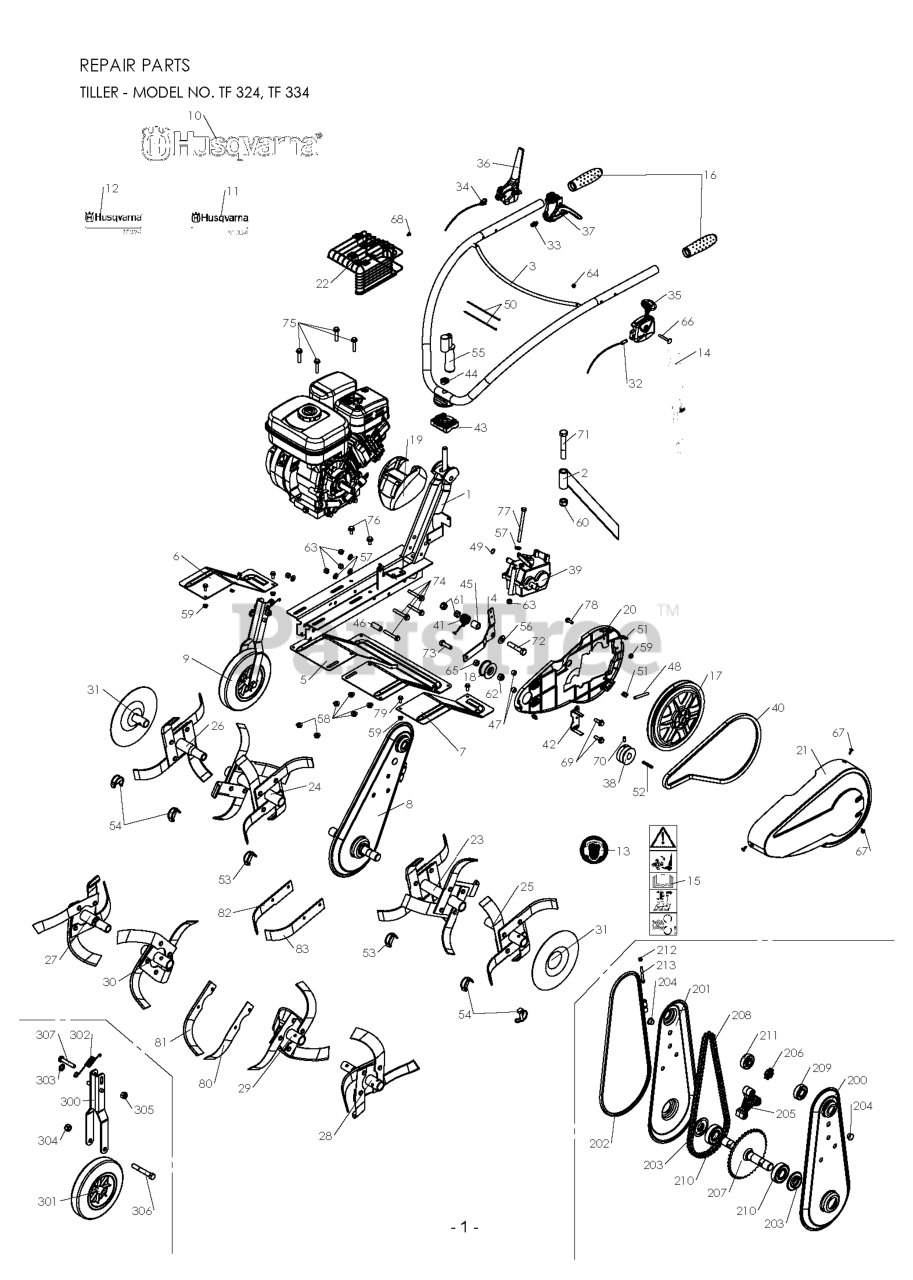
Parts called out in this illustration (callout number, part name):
4	ARM
49	RETAINING RING
64	Blocking nut M 6 Z
212	Blocking nut M 6 Z
